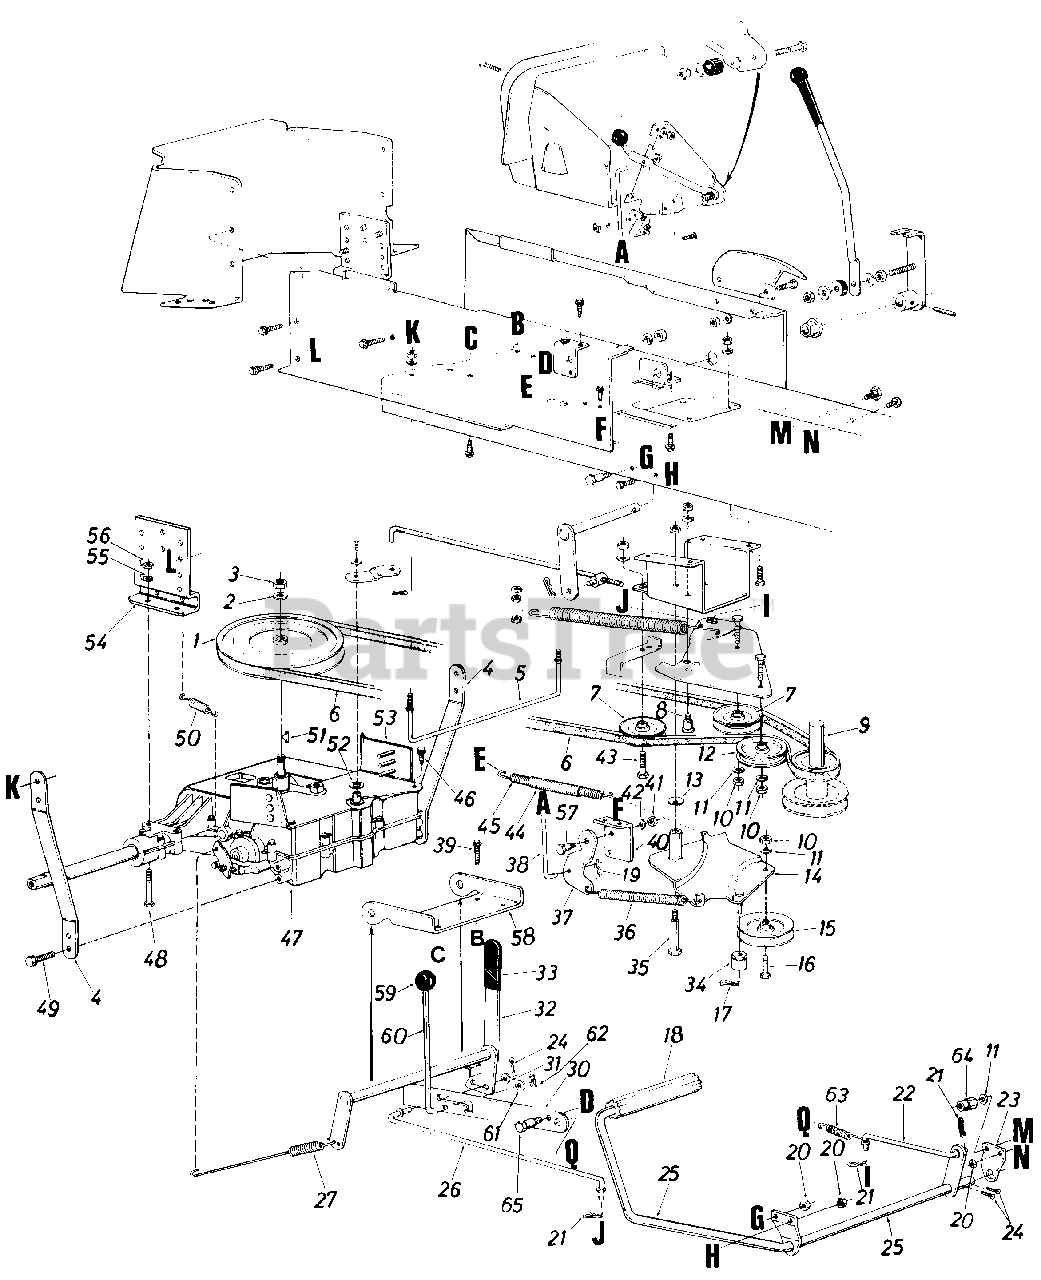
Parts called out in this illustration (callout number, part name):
1	8" "V"-Pulley
2	L-Wash. 1/2" I.D.
3	Hex Nut 1/2-20 Thd.
4	Transaxle Brace
5	Belt Guard
6	"V"-Belt
7	"V"-Belt Idler Pulley .38" I.D. x 3-1/16" O.D.
8	Shoulder Bolt .435" Dia. x .160 (5/16-18)
9	Two Step Engine Pulley 3.10" & 5.56" Dia.
10	Hex Nut 3/8-16 Thd.
11	L-Wash. 3/8" I.D.
12	Flat Idler Pulley 2.75" O.D.
13	Belleville Wash. .400" I.D. x .88" O.D. x .063
14	Idler Bracket Ass'y.
15	4" "V"-Idler Pulley
16	Hex Bolt 3/8-16 x 1.25" Lg.
17	Hairpin Cotter 5/16" Dia.
18	Foot Pad
19	Intern. Cotter Pin 5/16" Dia.
20	Hex Cent. L-Nut 3/8-16 Thd.
21	Hairpin Cotter 3/32" Dia. x 3/4" Lg
22	Brake Clutch Rod (4.60" Lg.)
23	Clutch Rod Bearing Brkt.
24	Cotter Pin 1/8" Dia. x 1.00" Lg.
25	Clutch Brake Pedal Ass'y.
26	Brake Cam Rod (13.60" Lg.)
27	Extension Spring .59" O.D. x .93" Lg.
30	Parking Brake Cam
31	Fl-Wash. .406" I.D. x 1.00" O.D. x .030 Thk.
32	Hand Brake Lever Ass'y.
33	Grip Flat Bar 11/4" Wide
34	Spacer
35	Shoulder Bolt .496" Dia. x 2.00" Lg. (3/8-16)
36	Extension Spring .75" O.D. x 6.12" Lg.
37	Deck Control Brkt.
38	Deck Control Rod
39	Hex Wash. Hd. TT-Tap Scr. 1/4-20 x 1.50" Lg.
40	Parking Brake Cam Mtg. Brkt.
41	Hex Nut 5/16-18 Thd.
42	L-Wash. 5/16" I.D.
43	Hex Bolt 3/8-24 x 1.50" Lg. (Grade 5)
44	Convoluted Conduit .50" I.D. x 4.0" Lg.
45	Ext. Spring .50" O.D. x 6.37" Lg.
46	Hex Wash. Hd. AB Tap Scr. 5/16-24 x .75" Lg.
47	Transaxle
48	Hex Bolt 5/16-18 x 2.50" Lg.
49	Hex Wash. Hd. AB Tap Scr. 5/16-24 x .75" Lg.
50	Extension Spring .50" O.D. x 2.75" Lg.
51	Hi-Pro Key 3/32" x 5/8" Dia.
52	Special Wash. 1.00" O.D.
53	Transaxle Belt Keeper Ass'y.
54	Transaxle Support Bracket
55	L-Wash. 5/16" I.D.
56	Hex Nut 5/16-18 Thd.
57	Shoulder Bolt .437" Dia. x .162" Lg. (5/16-18)
58	Idler Mtg. Brkt.
59	Ball Knob
60	Parking Brake Link
61	Fl-Wash.
62	Hairpin Cotter
63	Ext. Spring 3.12" Lg.
64	Spacer Nut 3/8-16 Thd.
65	Shld. Bolt .435" Dia. x .16"
